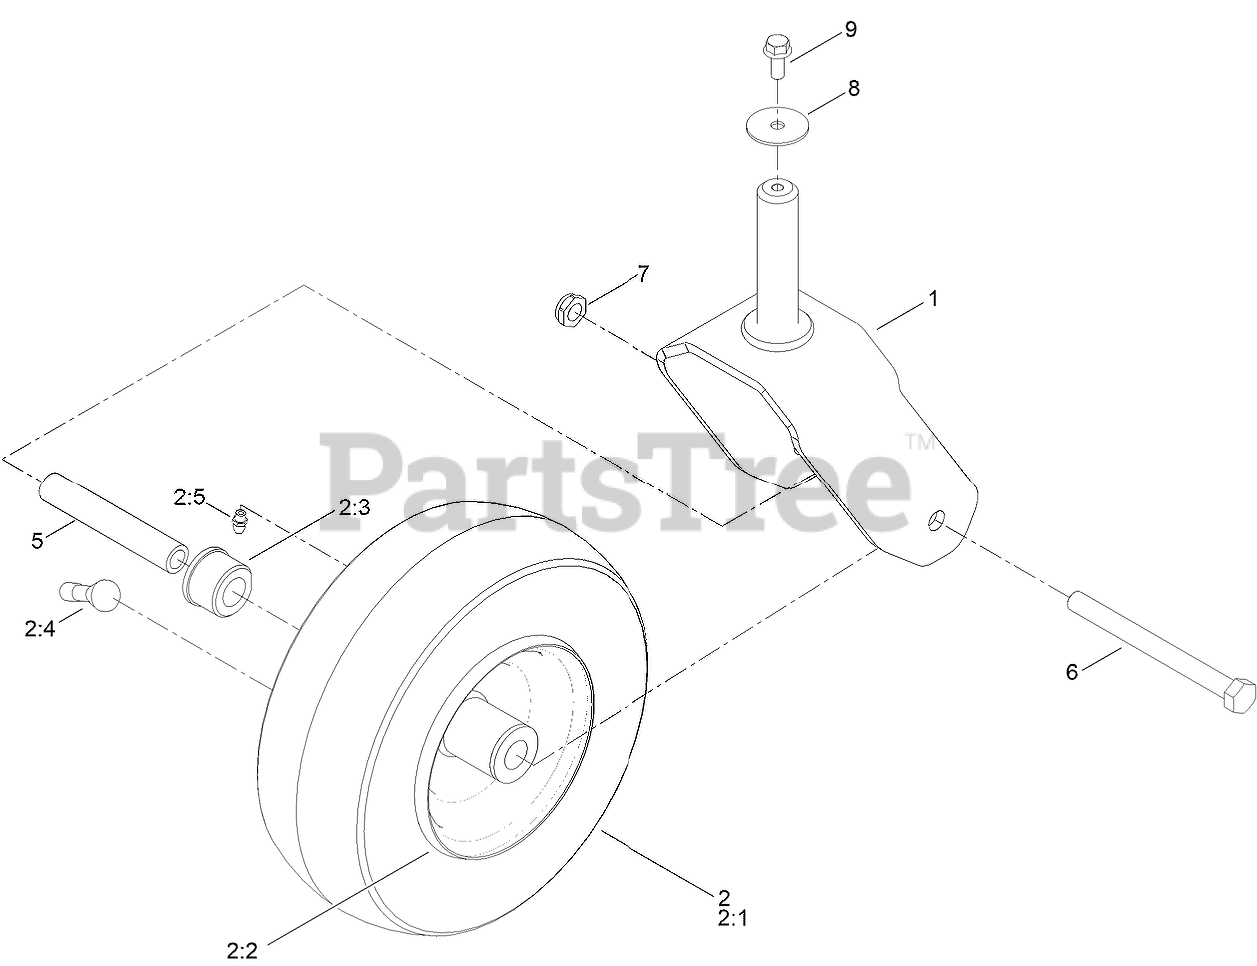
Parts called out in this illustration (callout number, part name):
1	FORK ASM
2	TIRE ASM
2:3	BUSHING-FLANGE
2:5	FITTING-GREASE
5	BUSHING-SPANNER
6	SCREW-HH
7	NUT-HEX
8	WASHER-FLAT
9	SCREW-HHF
